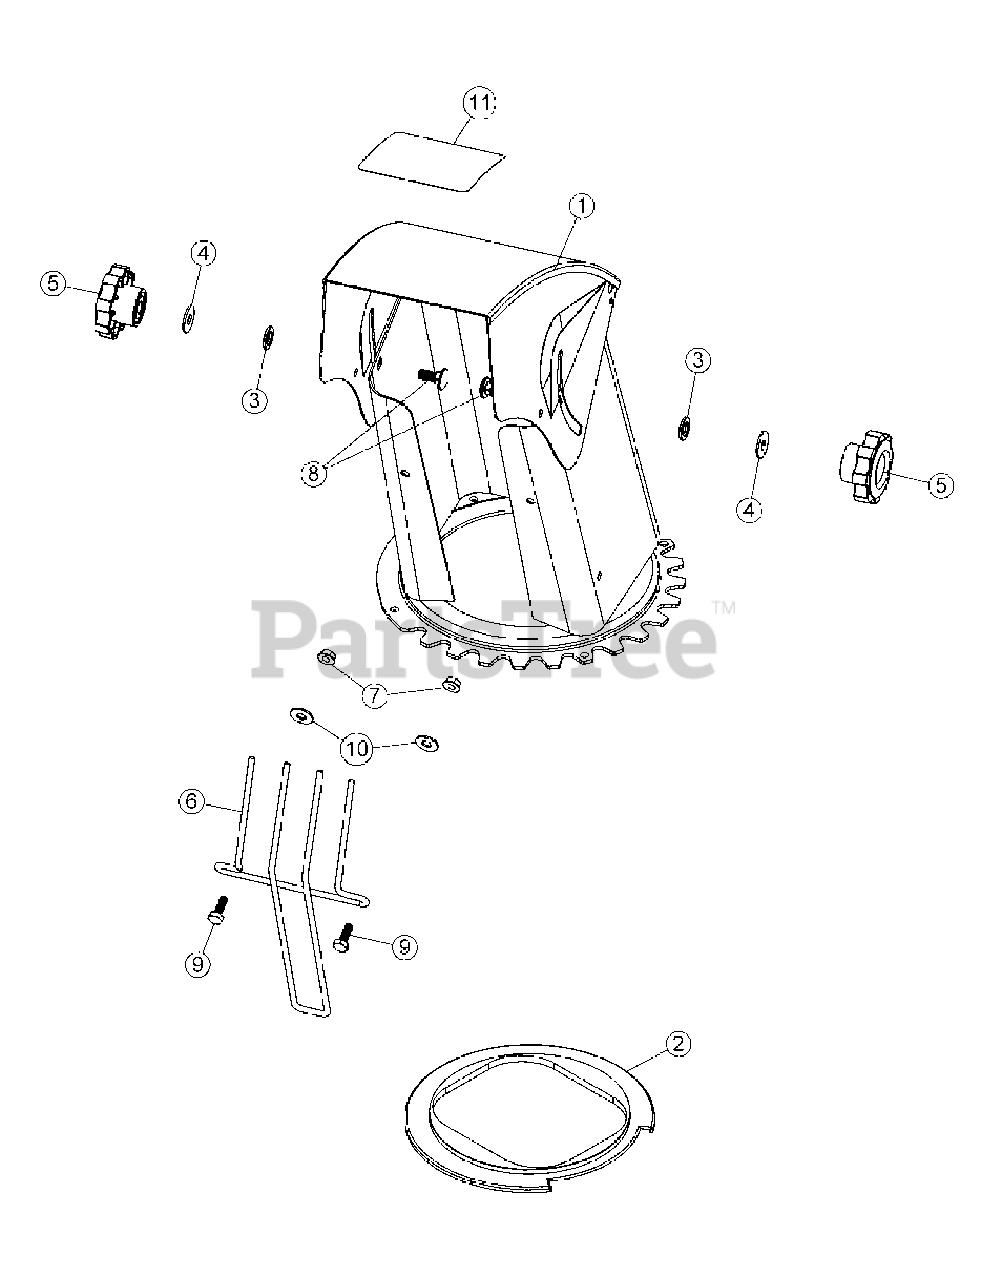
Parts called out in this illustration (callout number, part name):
1	Chute
2	Rotation ring
3	Nylon flat washer 7/16"
4	Nylon flat washer 11/32"
6	Hand guard
7	Flange nut 1/4" n.c.
8	Carriage bolt 5/16" n.c. x 3/4"
9	Hex. bolt 1/4" n.c. x 3/4"
10	Flat washer 5/16" hole
11	Danger decal chute
